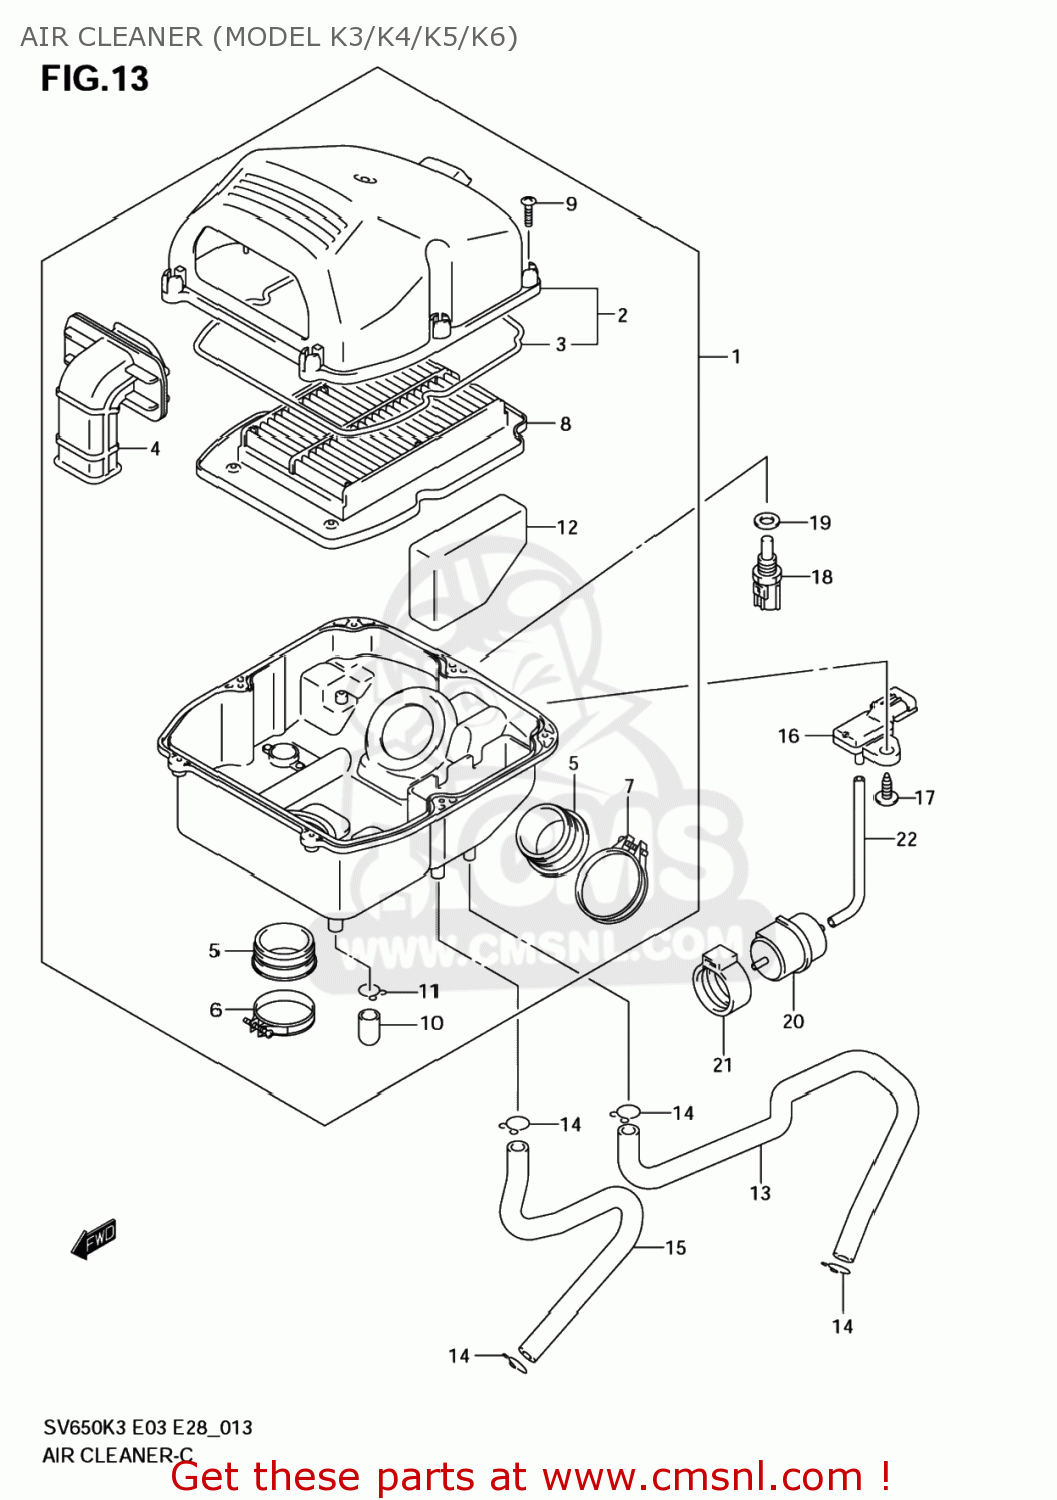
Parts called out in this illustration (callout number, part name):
1	CLEANER ASSY,AIR
2	CAP,AIR CLEANER
3	GASKET (NAS)
4	TUBE,INLET
5	TUBE,OUTLET
6	CLAMP
7	CLAMP
8	FILTER
9	SCREW
10	PLUG
11	CLIP
12	FILTER,BREATHER
13	TUBE,BREATHER CRANKCASE
14	CLIP
15	TUBE,BREATHER CYLINDER
16	SENSOR,BOOST
17	SCREW
18	SENSOR,WATER TEMP
19	GASKET(12X17X1) (NAS)
20	CHAMBER,VACUUM
21	BAND,VACUUM CHAMBER
22	HOSE(3.5X7.5X600)
